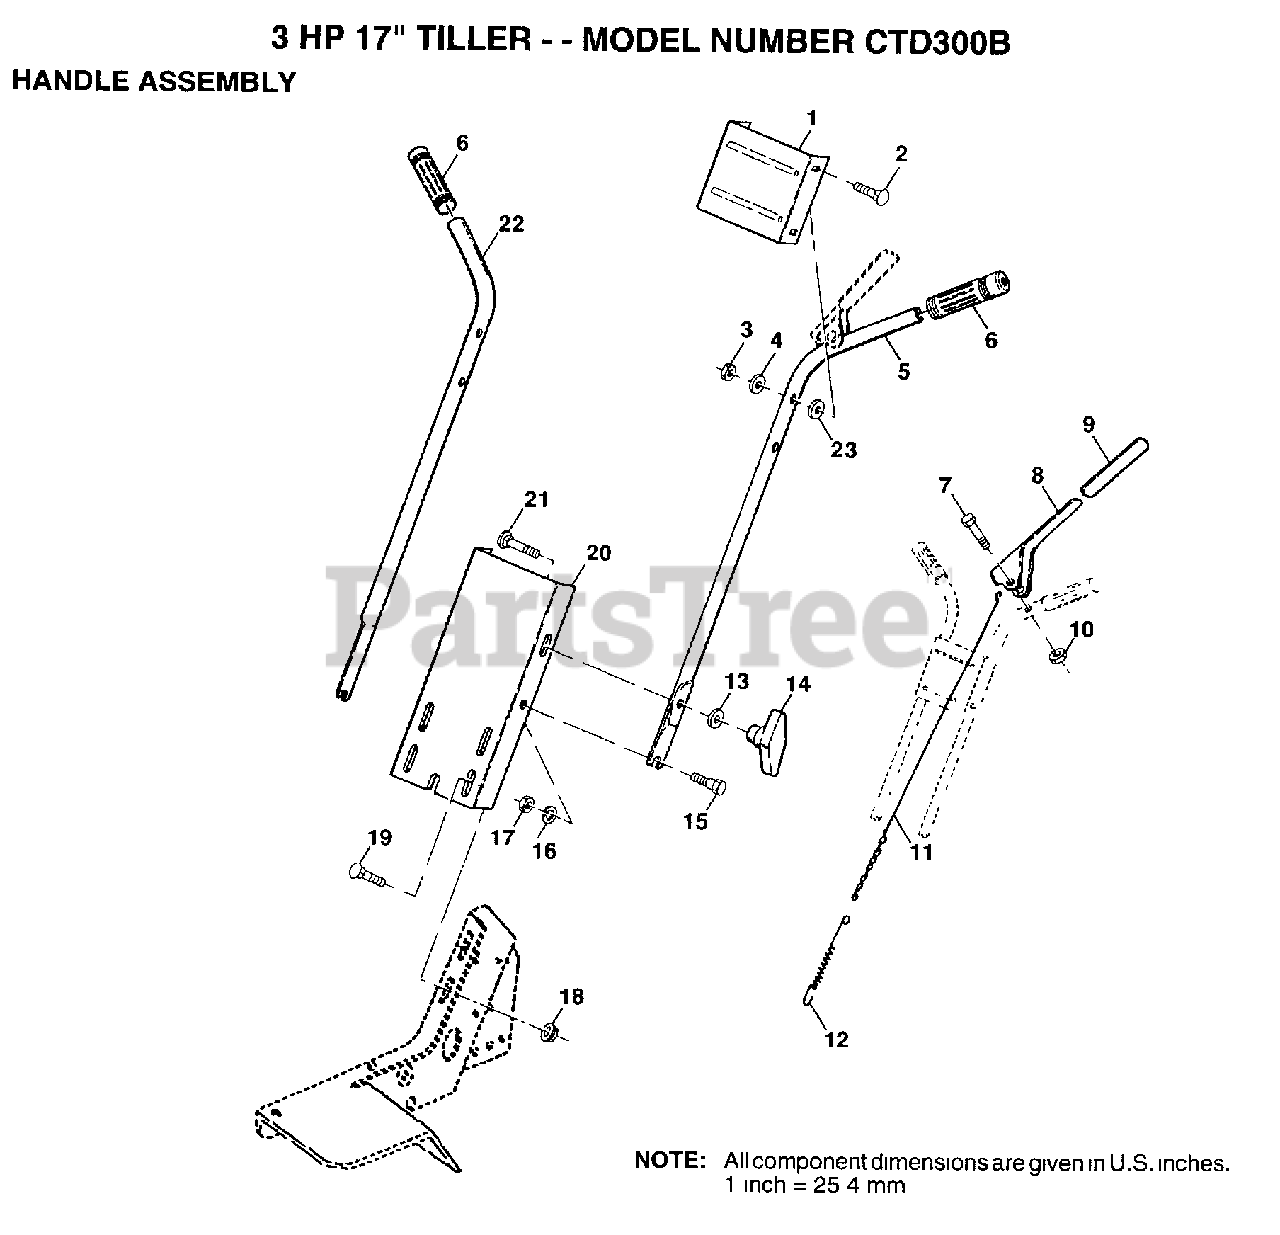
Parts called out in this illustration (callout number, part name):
2	BOLT
4	WASHER
6	GRIP NUB DOUBLE
7	BOLT.HEX.5/16-1.5
9	GRIP T
12	SPRING EXT TI
13	WASHER
14	KNOB HANDLE
16	LOCKWASHER
17	NUT.HEX.5/16-18
18	NUT
19	BOLT
21	BOLT
23	WASHER
